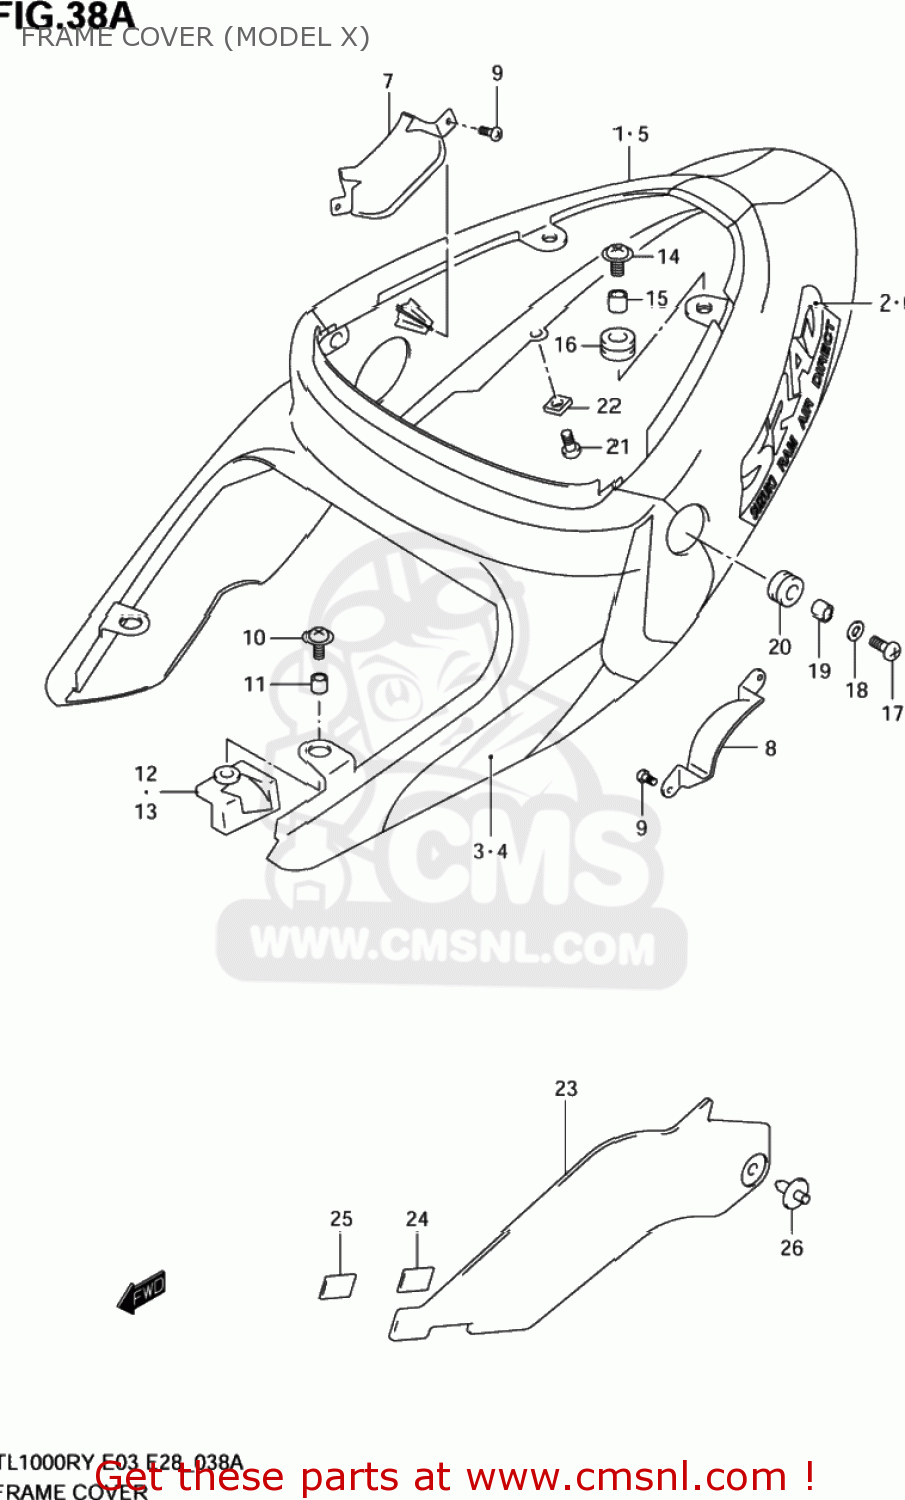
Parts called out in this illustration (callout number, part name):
1	COVER,FRAME (WHITE)
2	EMBLEM,FRAME COVER
3	TAPE SET,FRAME COVER,R
4	TAPE SET,FRAME COVER,L
5	COVER,FRAME
6	EMBLEM,FRAME COVER
7	CAP,FRAME COVER HOLE,R
8	CAP,FRAME COVER HOLE,L
9	SCREW
10	SCREW(6X20)
11	SPACER(6.5X9X9)
12	CUSHION,FRAME COVER,R
13	CUSHION,FRAME COVER,L
14	SCREW(6X20)
15	SPACER(6.5X10X9.4)
16	CUSHION
17	SCREW(6X20)
18	WASHER(6.5X22X1.6)
19	SPACER(6.5X9X6.7)
20	CUSHION
21	CLIP
22	NUT
23	COVER,FRAME,FRONT,RIGHT
24	FASTENER,NO.1
25	FASTENER,NO.2
26	CLIP(GRAY)
